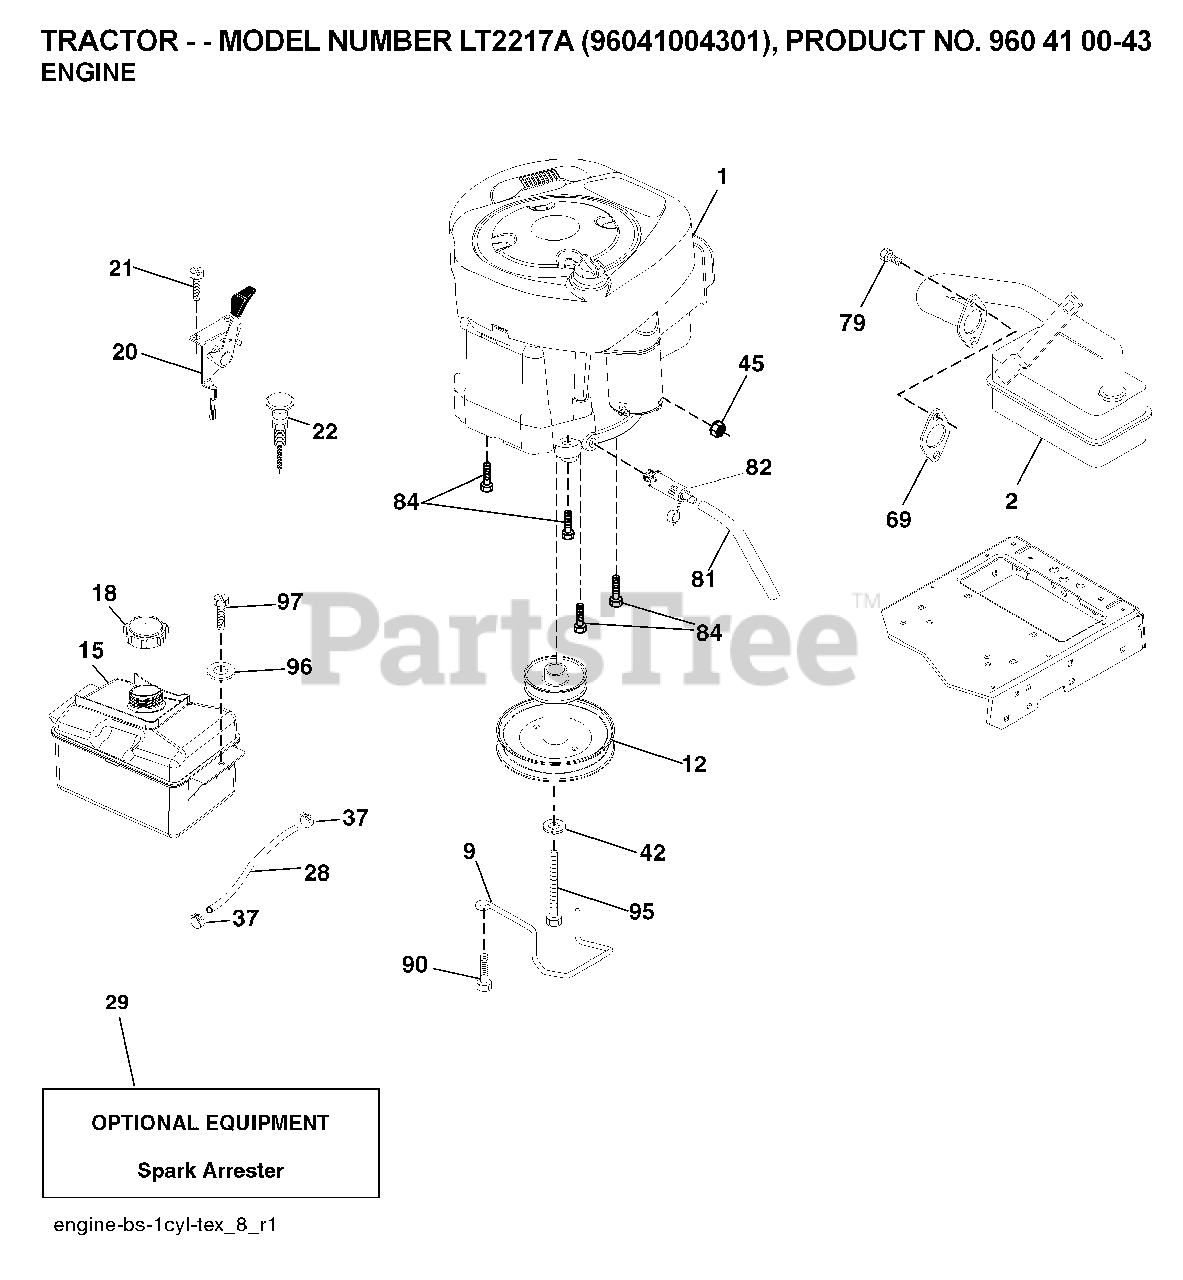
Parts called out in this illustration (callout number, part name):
9	KEEPER.BELT.ENGINE.3.25
12	PULLEY ENGINE
15	TANK FUEL FRT 1.5 GAL
18	FUEL CAP
20	CONTROL.TH/CK.C.
21	SCREW
28	LINE.FUEL.20
29	ARRESTER SPARK (OPTIONAL)
37	HOSE CLAMP
42	LOCKWASHER
45	NUT
69	REPL BY 532 27 22-93
79	SCREW.SOCKET HD.5/16-1
81	TUBE, DRAIN OIL ASM.
82	PLUG DRAIN OIL EASY
84	SCREW.3/8-16
90	SCREW 3/8-16X1
95	BOLT HEX 7/16-20X4-1/4"
97	SCREW HEXWSHR 1/4-20X3/4
